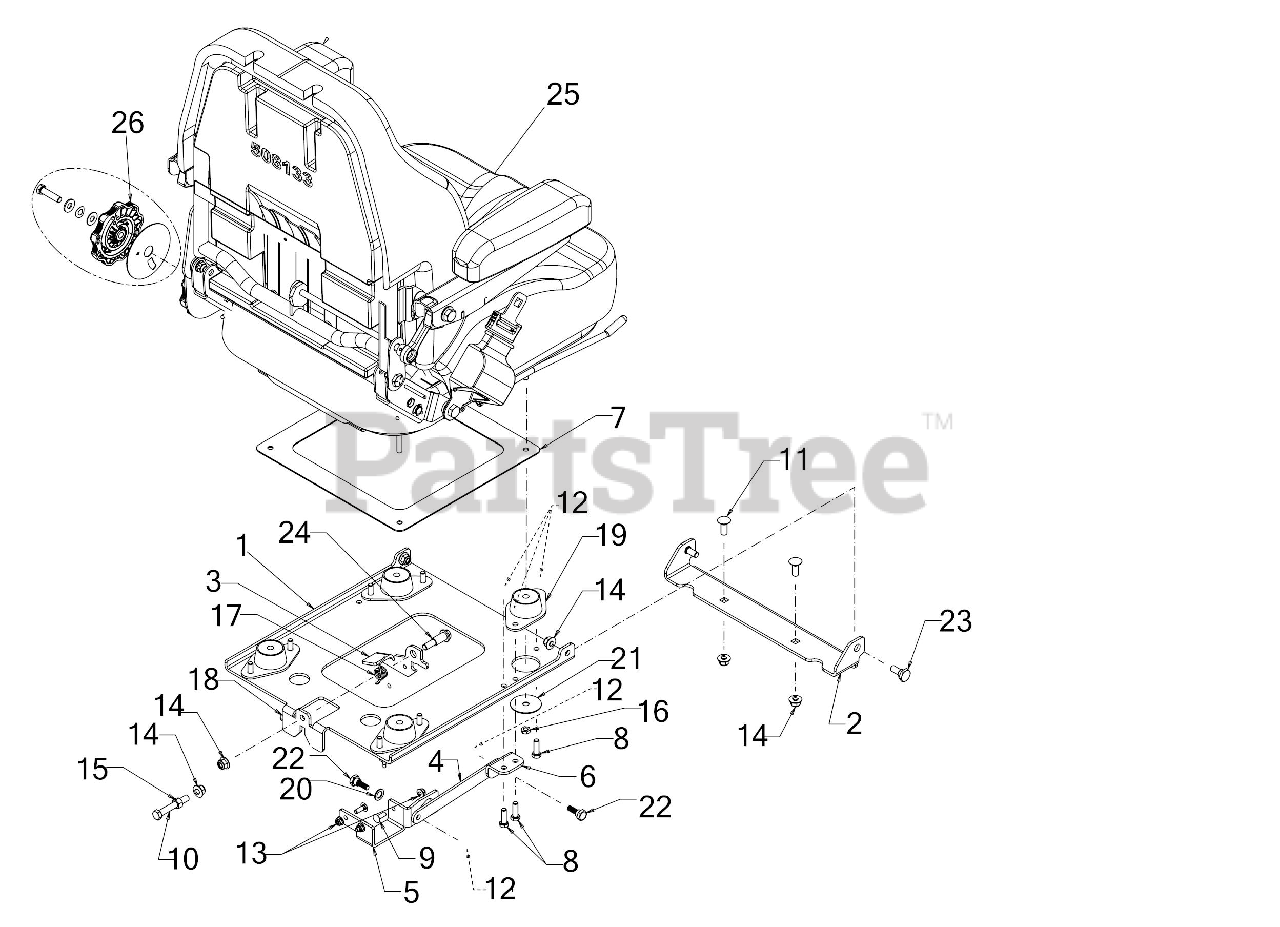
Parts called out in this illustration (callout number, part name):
1	SEAT MOUNTING BRACKET
2	SEAT PIVOT BRACKET
3	SEAT LATCH LEVER
4	SEAT LOCKOUT BRACKET
5	SEAT LOCKOUT MOUNT
6	LOCKOUT BRACKET
7	SEAT STABILIZER PLATE
8	SCREW 5/16-18 x 1.0 GR5
9	SCREW 1/4-20 x .75 GR5
10	HEX SCREW-3/8-16X2.5 GR5
11	CARRIAGE BOLT 3/8-16 x 1.00 GR5
12	FLANGE LOCK NUT
13	FLANGE LOCK NUT
15	HEX NUT
16	HEX NUT TOP LOCK 5/16-18 GR 8
17	TORSION SPRING
18	RUBBER BUMPER
19	SEAT MOUNT
20	FLAT WASHER .469X.750X.054
21	HUB CAP WASHER .406 x 1.92 x .060
22	SHOULDER SCREW .437
23	SHOULDER SCREW
24	SHOULDER SCREW .50X.925
25	SEAT ASSEMBLY W/ADJUSTABLE LUMBAR
26	SEAT KNOB KIT
